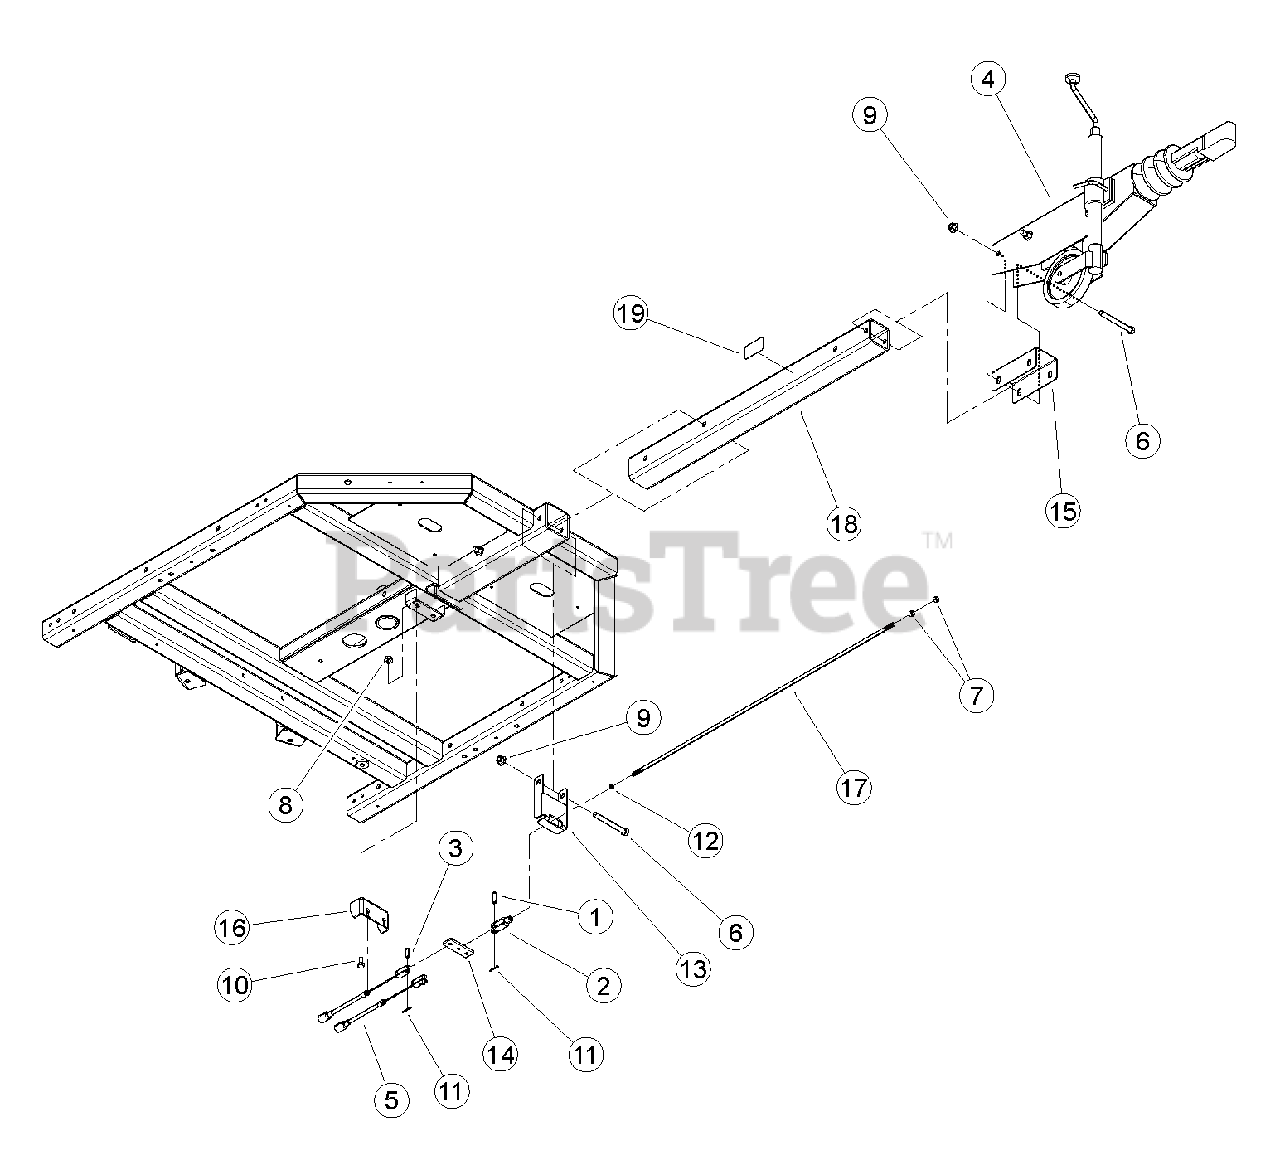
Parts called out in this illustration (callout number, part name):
1	PIN, CLEVIS-3/8 X 1-1/4 ZP
2	CLEVIS, ADJ ROD END 3/8-24UNF
3	PIN, CLEVIS 5/16 X 1
4	COUPLING, SURGE W/ JOCKEY WHEEL
5	CABLE, BRAKE
6	BOLT, 1/2 X 4-1/2" GR5 HHCS NC ZP
7	NUT, 3/8" HEX NC ZP
8	NUT, 7/16" SERRATED FLANGE NC ZP
9	NUT, 1/2-13 NYLOCK FLANGE
10	BOLT, 7/16 X 3/4 HHCS GR5 ZP
11	PIN, 1/8 X 1.00 ZP COTTER
12	NUT, 3/8 NC JAM ZP
13	BRACKET, ROD HANGER
14	BAR, BRAKE COMPENSATOR
15	CHANNEL, SPACER
16	WELDMENT,CABLE BRACKET
17	ROD, BRAKE
18	ASSEMBLY, HITCH POLE
19	REFLECTOR, WIDE ANGLE AMBER
